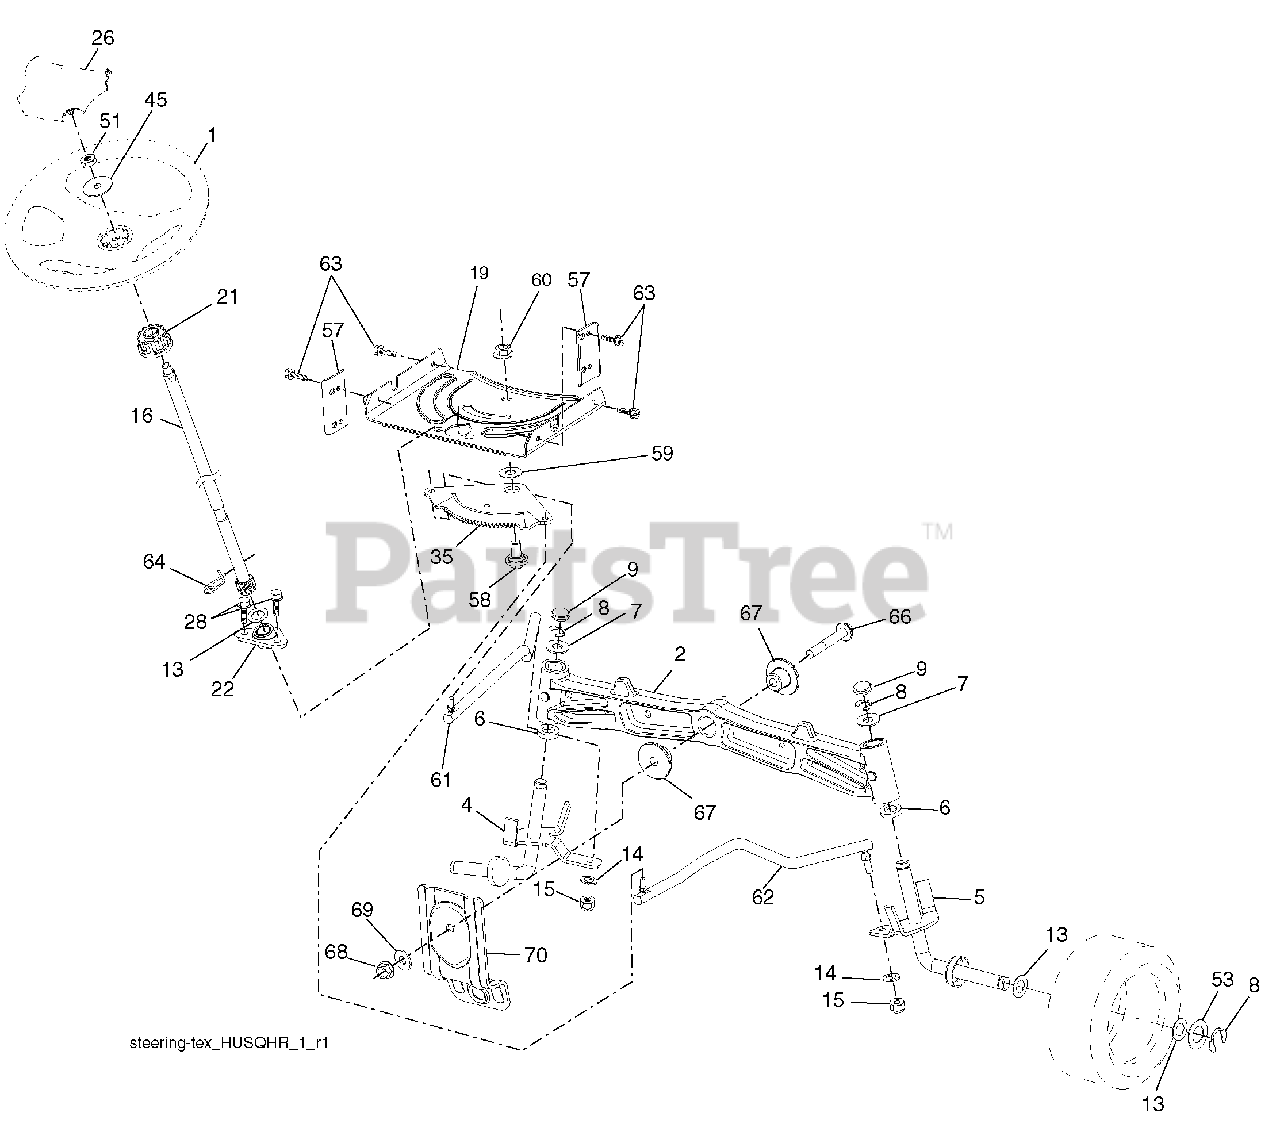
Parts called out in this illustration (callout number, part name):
1	Wheel, Steering
2	Axle Asm., Front
4	Spindle Asm., LH
5	Spindle Asm., RH
6	Bearing, Race Thrust Harden
7	Washer 25/32 x 1-5/8 x 16 Ga.
8	Ring, Klip #T5304-75
9	Cap, Spindle
13	Washer 25/32 x 1-1/4 x 16 Ga.
14	Washer, Lock Hvy Hlcl Spr 3/8
15	Nut, Crown Lock 3/8-24 unf
16	Shaft Steering
19	Plate Steering
21	Adapter, Wheel Steering
22	Strg. Supt. Lower
26	Insert, Wheel Steering
28	Screw 3/8-16 x 3/4
35	Gear, Sector Plate
45	Washer 9/16 ID x 2-3/8 OD 12 Ga.
51	Nut Hex Jam Toplock 1/2-20 unf
53	Washer Hardened .793 x 1.637 x .060
57	Bracket Upstop
58	Bolt Shoulder Sector Pivot CFM
59	Washer Thrust Sector Steering
60	Nut Flange Lock 5/8-11
61	Draglink LH
62	Draglink, RH
63	Screw 5/16-18 x 3/4
64	Retainer Clip Spring Steering
66	Bolt Hex Fghd 7/16-14 x 3 Serr
67	Bushing PM Front Axle
68	Nut Lock Flange 7/16-14 Gr. 5
69	Washer 1.5 x .505 x .118
70	Bracket Deck Susp. Front
